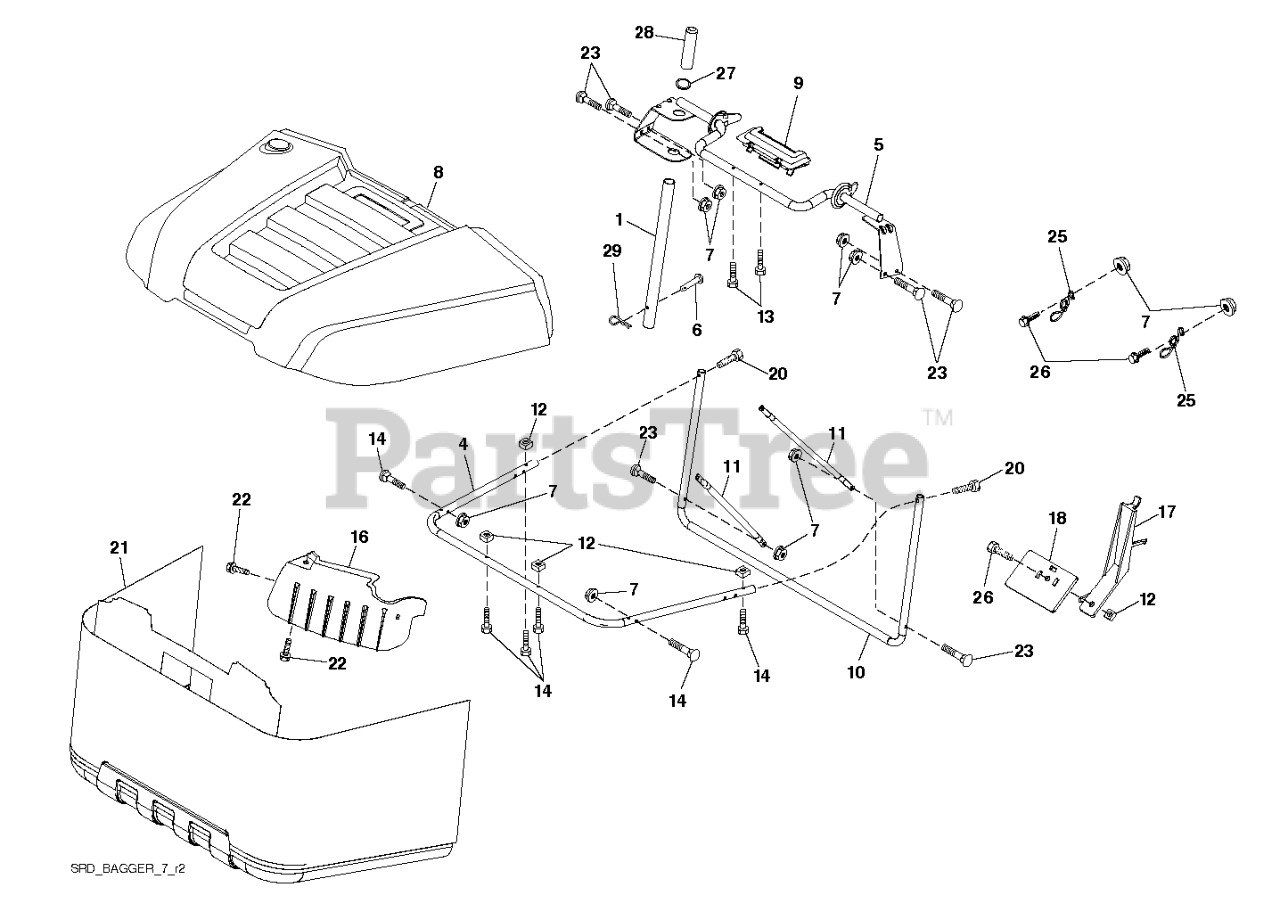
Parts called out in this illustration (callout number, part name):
1	TUBE.HANDLE.BAGGER.CRD/SRD.BLA
4	SUBASM.TOP.TUBE.TEX.CRD
5	FRAME.ASM.TOP.BAGGER.SRD
6	RIVET,DRILLED
7	NUT T
8	BAGGER.TOP.SUB.ASSEM.SRD
9	INSERT.HANDLE.BAGGER.(2 2)
10	FRAME.FRONT.SRD.BAGGER
11	TUBING.BRACE.BAGGER.SRD.BLACK
12	NUT.SQUARE.1/4
13	SCREW.1/4X1.150.HXWSH
14	BOLT.SHOULDER.HX.WSH.1/4X1.150
16	DEFLECTOR.BAGGER.SRD
17	LEVER.BAGGER.FULL.SRD.BLACK
18	PADDLE.BAGGER.FULL.SRD.BLACK
20	SCREW.HEXCAP.1/4-20X1.375(2 2)
21	BAG.ASM.BAGGER.SRD.HUSQVA.GREY
22	SCREW.HI-LO.CONSOLE
25	SPRING.LATCH.BAGGER.SRD
26	SCREW HEX CRT
27	RB GROMMET.RUBBER.SRD
28	GRIP.HANDLE.BLACK
29	PIN.COTTER.5/16.BOW TI
